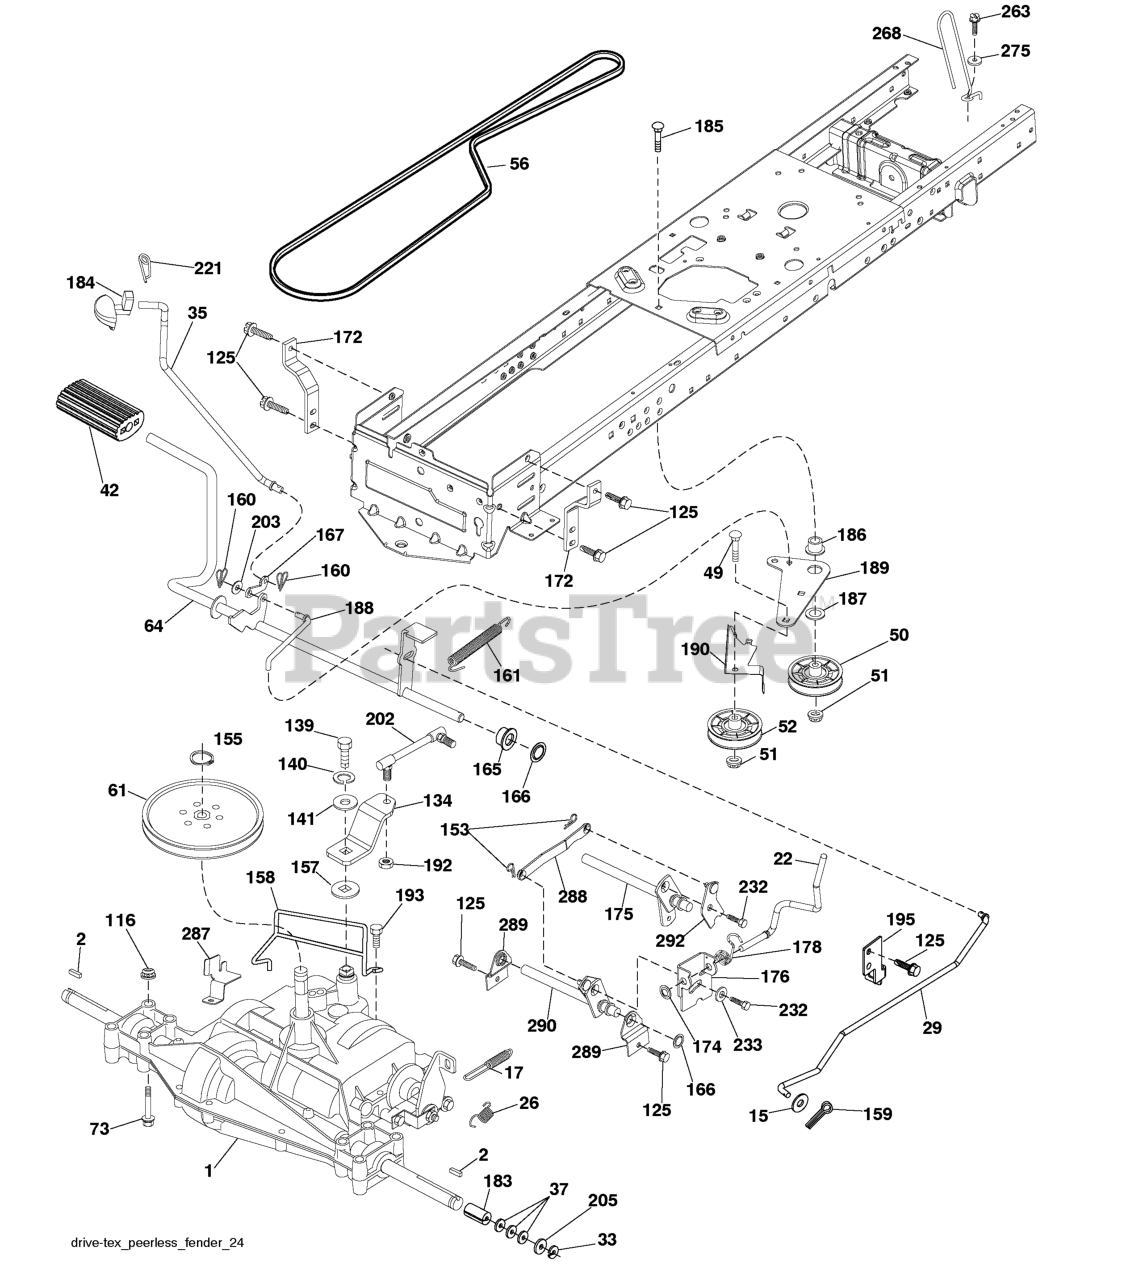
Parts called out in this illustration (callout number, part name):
2	SQUARE KEY
15	WASHER
17	SPRING.BRAKE.PEERLESS.TEX
22	SHIFTER.ASM.HANDLE.SRD
23	KNOB.DUCKHEAD.1/2
26	SPRING.BRAKE.RTN.GR.DR
29	ROD.BRAKE.PEERLESS
35	ROD.CNTRL.PARK.PREDATOR.LT.TEX
42	PEDAL COVER T
50	IDLER.FLAT.910.OFFSET
51	NUT LOCK FLG 3/8-16 UNC
52	IDLER.V-GROOVE.910.OFFSET
56	BELT, V GROUND DRIVE 95 25
61	PULLEY
64	SHAFT.ASM.PEDAL.BRAKE.
73	BOLT HEX 5/16-18 GR 5
116	NUT LOCK HEX FLANGE 5/16-18
125	SCREW
139	BOLT 1/4-28X3/4
140	LOCKWASHER
141	WASHER LT
153	RETAINER M
155	RETAINING RING LT
157	WASH-SHFT PLT LT
158	KEEPER.PMS.18/20.D4365
159	COTTER PIN
160	RETAINER CLIP
161	SPRING, RETURN LT
165	BUSHING.SHAFT.BRAKE.HAND
166	NUT.PUSH.625
167	LATCH.BRAKE.SPRING
172	STRAP.TRQ.LH.GEAR.DRIV
174	NUT.PUSH.500.2006
175	SHAFT ASM SHIFT
176	ARM.CLEVIS.ROD.SHIFT
178	SPRING.TORSION.LIFT.HANDLE
183	SPACER AXLE
184	HANDLE PARKING BRAKE
186	SPACER.RETAINER
187	WASHER 12/32X2X10GA
188	RP.LINK.CLUTCH.GROUND.DRIVE
189	BELLCRANK.GROUND.DRIVE.TEX.
190	KEEPER.BELLCRANK.DRIVE
192	NUT LOCK CENTER 1/4 -28 FNTHD
193	SCREW 5/16"
195	BRKT.ROD.BRAKE.PEERLES
202	LINK.SHIFT.PMST.18" (SPG1286)
203	WASHER
221	RETAINER.SPRING.CLIP.H
232	BOLT FIN HEX 7/16-14 X 1
233	WASHER SERRATED
263	SCREW, 3/8-16X3/4
268	WASHER
275	GUARD MUFFLER
287	KEEPER.PULLEY.T/A.7.04
288	LINK.SHIFT.SLAVE.SRD
289	BRACKET.SUPPORT.SHIFT.OUTER
290	SHAFT.ASM.SHIFT.REAR.SRD
292	PLATE.ASM.SHIFT.FWD.SRD
